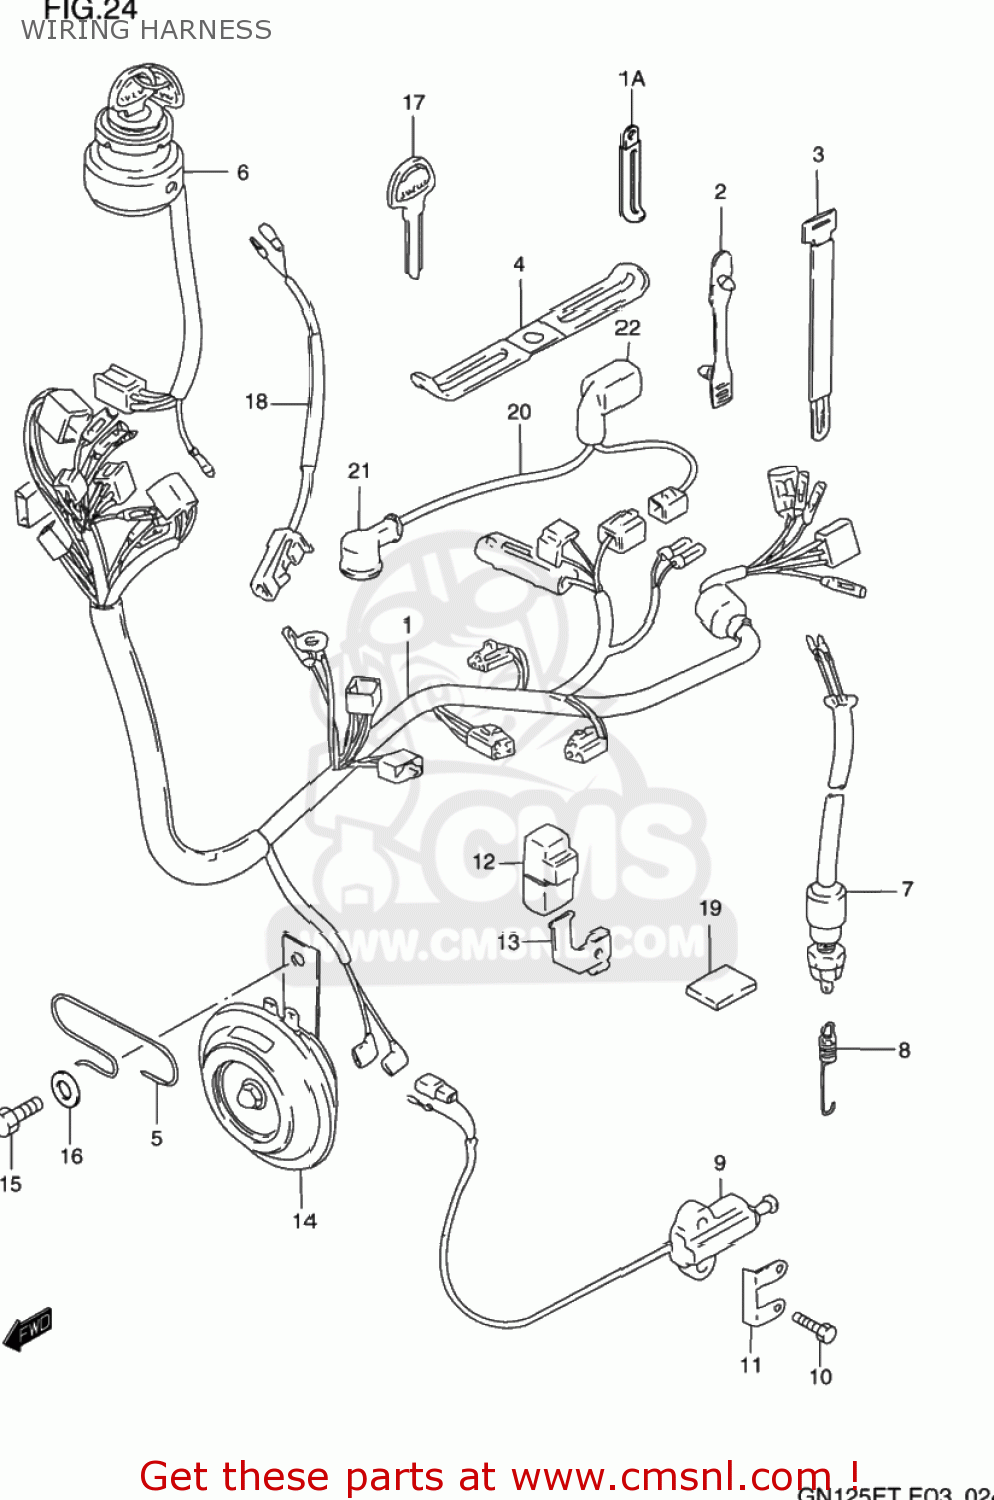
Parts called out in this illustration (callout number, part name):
1	HARNESS,WIRING
1A	CLAMP
2	CLAMP,L:88
3	CLAMP
4	CLAMP,WIRING HARNESS
5	CLAMP,WIRING HARNESS
6	SWITCH ASSY,IGNITION
7	SWITCH ASSY,STOP LAMP
8	SPRING
9	SWITCH ASSEMBLY,SIDE STAND
10	BOLT
11	PROTECTOR,SIDE STAND SWITCH
12	RELAY ASSY
13	BRACKET,SIDE STAND RELAY
14	HORN ASSY
15	BOLT
16	WASHER
17	KEY,BLANK
18	WIRE,CLUTCH SWITCH LEAD
19	TAPE
20	WIRE,BATTERY PLUS LEAD
21	CAP,STARTER RELAY
22	CAP,BATTERY PLUS TERMINAL
